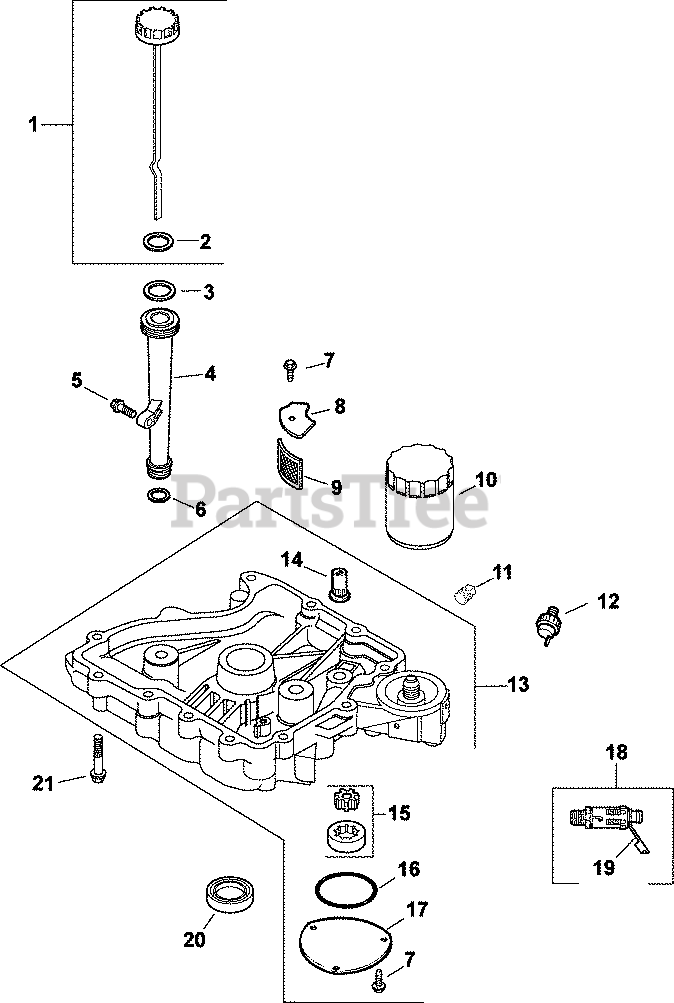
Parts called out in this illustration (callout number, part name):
1	DIPSTICK/CAP ASSY (BLACK)
2	O-RING, DIPSTICK
3	O-RING, UPPER OIL FILL TUBE
4	TUBE, OIL FILL USE 25 123 07-S
5	SCREW,FLG THD FRM M6X1.0X20-(#25086396S)
6	O-RING, LOWER OIL FILL TUBE
7	SCREW,FLG THD FRM M5X0.8X16-(#25086398S)
9	SCREEN, OIL-USE 24 162 26-S
10	OIL FILTER
11	PLUG, SQ HD PIPE 3/8"
12	SENSOR, OIL PSI
13	PAN, OIL
14	VALVE, OIL PRESSURE RELIEF
15	PUMP ASSEMBLY, OIL - DISCONTINUED
16	O-RING (2.5" DIA)
17	COVER, OIL PUMP
18	CAP, OIL DRAIN VALVE
19	CAP, OIL DRAIN VALVE
20	SEAL, OIL
21	SCREW, FLG M8X1.25X45
